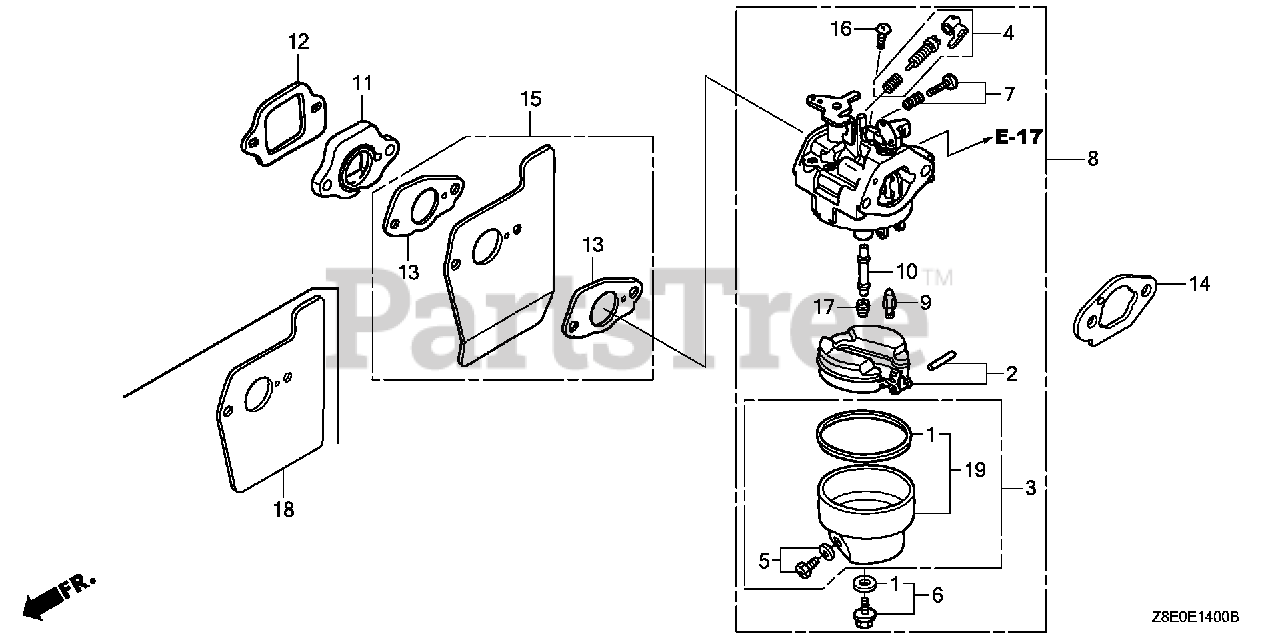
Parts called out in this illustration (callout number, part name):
1	GASKET SET
6	SCREW SET
8	CARBURETOR ASSY. (BB65R A)
9	VALVE, FLOAT
10	NOZZLE, MAIN
11	INSULATOR, CARBURETOR
12	GASKET, INSULATOR
14	GASKET, CARBURETOR
16	SCREW, PAN (5X6)
17	JET, MAIN (#62)
17	JET, MAIN (#65)
17	JET, MAIN (#68)
18	GUIDE, AIR
19	CHAMBER SET, FLOAT (CARBURETOR NO.)
